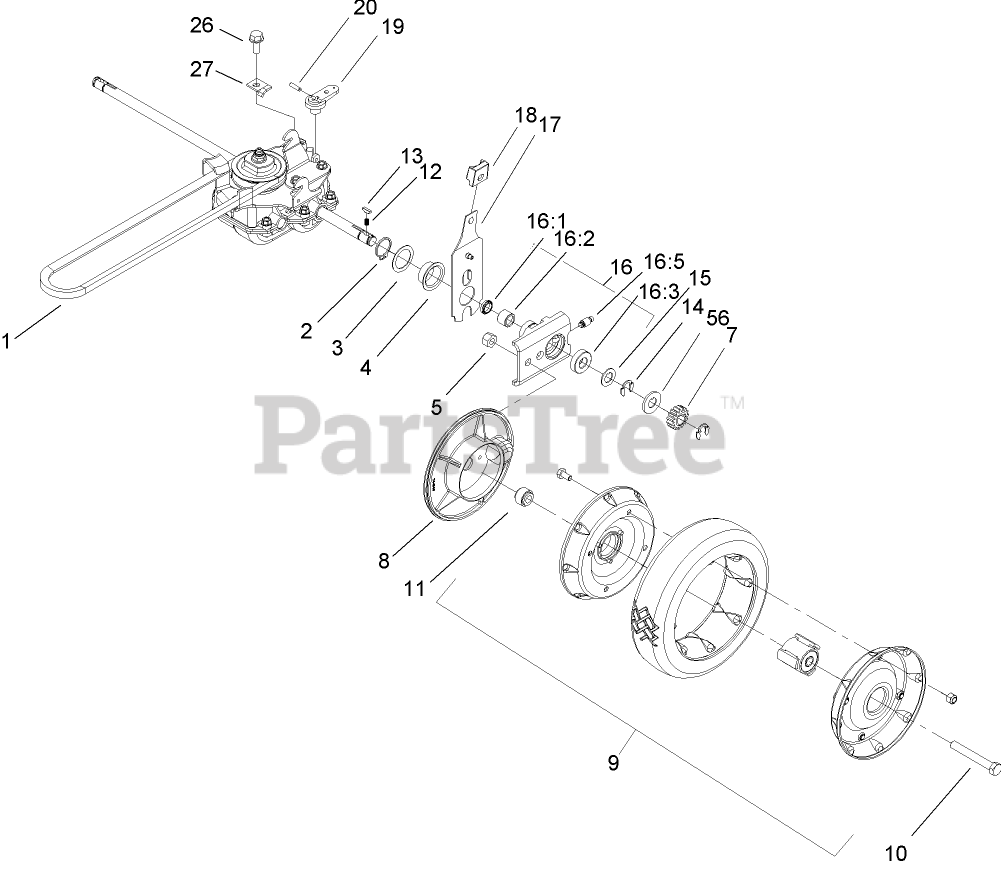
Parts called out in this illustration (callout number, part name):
1	V-BELT
2	RING-RETAINING
3	WASHER
4	CAP-END
5	NUT-LOCK, CONE
7	GEAR-PINION
8	COVER-WHEEL
9	WHEEL AND TIRE ASM
10	SCREW-HH
11	SPACER-COVER, WHEEL
12	SPRING-COMPRESSION
14	RING-RETAINING
15	WASHER-THRUST, OUTER
16	PIVOT ARM ASM
16:1	SEAL-OIL
16:2	BEARING-ROLLER
16:3	BEARING-WHEEL
17	REAR SPRING ARM ASM
18	KNOB-ARM
19	LEVER-SHIFT
20	PIN-COIL
26	SCREW-HWHTF
27	CLAMP-CABLE
56	WASHER-THRUST, OUTER
